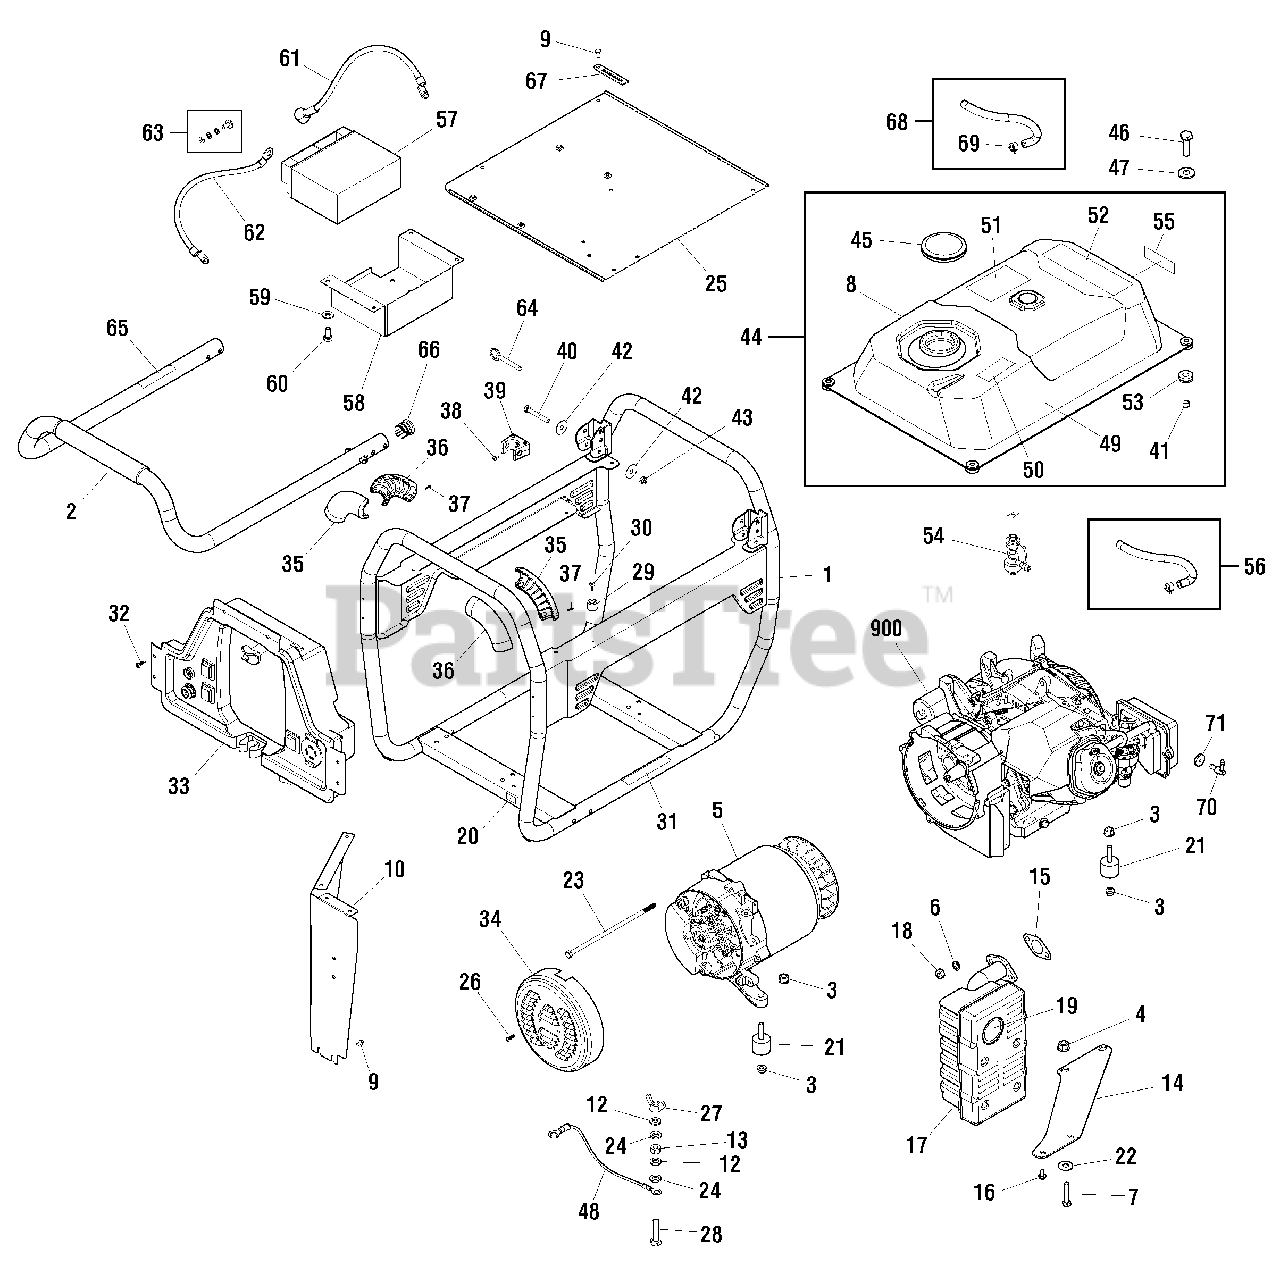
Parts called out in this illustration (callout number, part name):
5	ALTERNATOR
6	* WASHER, Lock, 3/8
7	* CAPSCREW, Hex Head, M10-1.5 x 45
9	* CAPSCREW, Hex Head, M6-1.0 x 10
12	* WASHER, Lock, 1/4
13	* NUT, M6-1.0
15	GASKET-EXHAUST
16	* CAPSCREW, Hex Head, M6-1.0 x 12
18	* NUT, M8 - 1.25
21	MOUNT-VIBRATION
22	WASHER
24	* WASHER, M6
28	* CAPSCREW, Hex Head, M6-1.0 x 25
33	PANEL-CONTROL
34	COVER-REAR BEARING
44	TANK-FUEL
47	* WASHER, Flat, 1/4
56	KIT-FUEL HOSE (Cut to fit)
63	KIT-BATTERY HARDWARE
68	HOSE-VAPOR (Cut to fit)
900	** ENGINE
